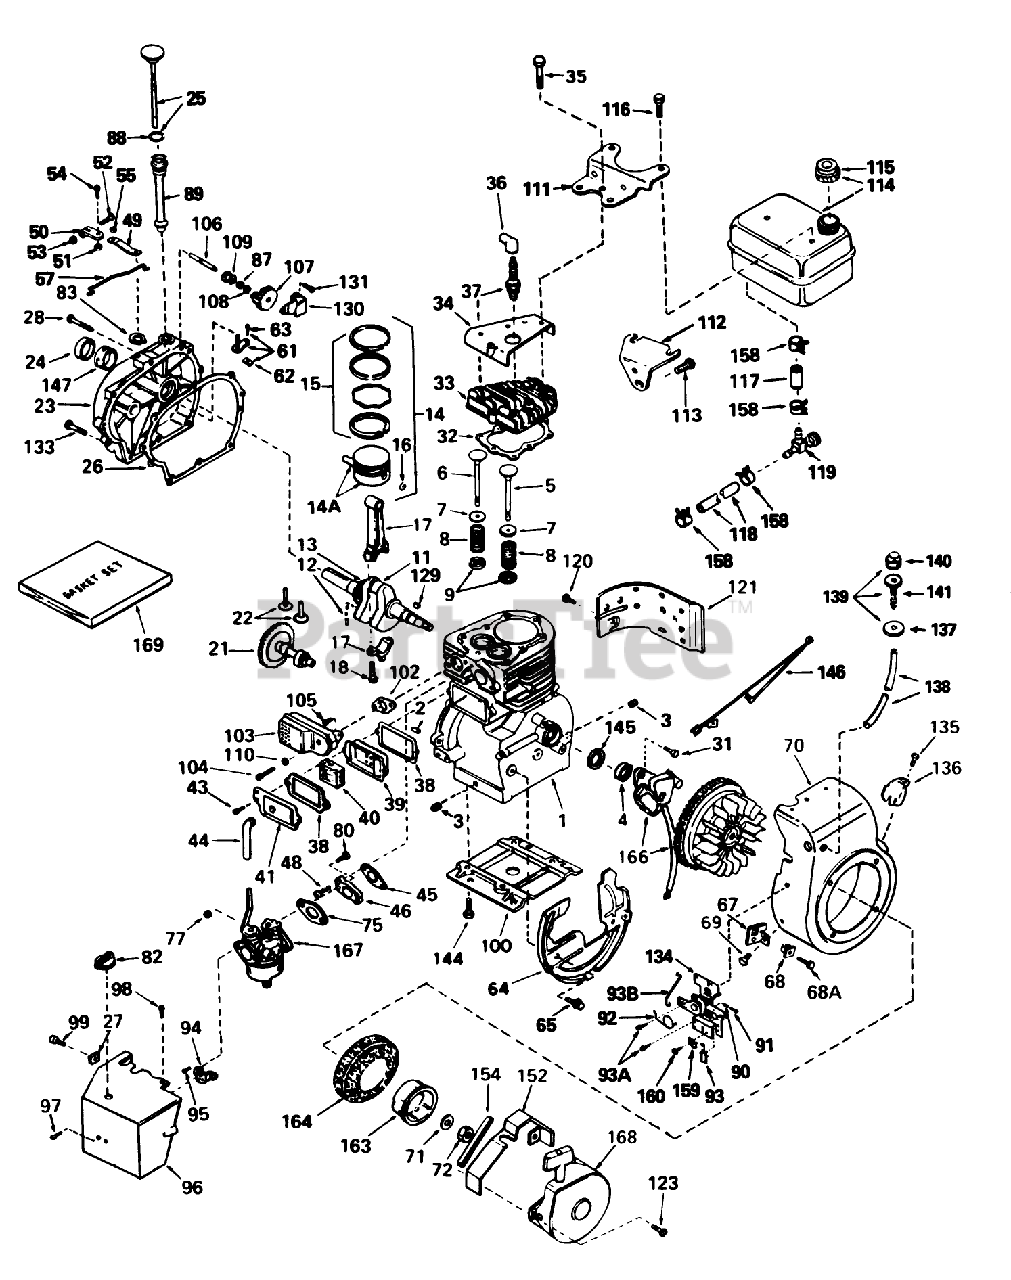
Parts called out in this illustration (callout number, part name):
1	Cylinder Assy. (Incl. Ref. #2, 3, 4 5)
2	Pin-Dowel
3	Plug-Drain, Oil (SQH 1/4-18)
4	Seal, Oil
5	Valve, Intake (Standard)(Incl. No. 9)
5	Valve, Intake (1/32" oversize)(Incl. No. 9)
6	Valve, Exhaust (Standard)(Incl. No. 9)
6	Valve, Exhaust (1/32" oversize)(Incl. No. 9)
7	Cap-Spring, Valve
8	Spring-Valve
9	Keeper-Spring, Valve
11	Crankshaft Assy. (Incl. Nos. 12 13)
12	Pin, Groove
13	Gear-Crankshaft
14	Piston, Pin Ring Assy. (Std.)(Incl. Ref. #14A, 15 16)
14	Piston, Pin Ring Assy. (.010 Oversize)(Incl. Ref. #14A, 15 16)
14	Piston, Pin Ring Assy. (.020 Oversize)(Incl. Ref. #14A,15 16)
14A	Piston Pin Assy. (Std.)(Incl. Ref. #16)
14A	Piston Pin Assy. (.010 Oversize)(Incl. Ref. #16)
14A	Piston Pin Assy. (.020 Oversize)(Incl. Ref. #16)
15	Ring Set, Piston (Std.)
15	Ring Set, Piston (.010 Oversize)
15	Ring Set, Piston (.020 oversize)
17	Rod Assy., Connecting (Incl. Ref. #18)
18	Bolt, Connecting Rod
21	Camshaft, BCR
22	Lifter-Valve
23	Cover, Cylinder (Incl. Nos. 24 106)
24	Oil Seal
25	Dipstick, Oil (Incl. Ref. #88)
26	Gasket-Cover, Cylinder
27	Nut-U Type
28	Screw (1/4-20 x 1-1/4)
31	Screw
32	Gasket-Head, Cylinder
33	CYLINDER HEAD
34	Cover-Head, Cylinder
35	Screw (5/16-18 X 2-1/2)
36	Cover-Spark Plug
37	Plug, Spark (J17LM or equiv.)
37	Plug, Spark (Champion RCJ-8)
38	Gasket-Breather
39	Body-Breather
40	Element-Breather
41	Cover-Valve
43	Screw
44	Tube-Breather
45	Gasket-Intake
46	Flange, Carburetor (Incl. Nos. 77 80)
48	Screw
49	Lever-Governor
50	Clamp-Lever, Governor
51	Nut-Lock
52	Screw
53	Nut-Lock
54	Screw
55	Washer-Lock
57	Governor Link
61	Rod, Governor (Incl. Nos.62 63)
62	Yoke-Governor
63	Screw (6-40x5/16)
64	Baffle Blower Housing
65	Screw (1/4-20x19/32)
67	Bracket
68	Grommet
68A	Screw
69	Screw, Hex Hd.
70	Housing, Blower (Incl. Ref. #135 136)
71	Washer
75	Gasket-Carburetor
77	Nut and Lock Washer (1/4-28)
80	Screw
82	Knob-Control
83	Ring-Retaining
87	Washer-Flat
88	O-Ring
89	Tube Fill
90	Spring-Compression
91	Screw
92	Spring-Throttle
93	Terminal
93A	Screw (10-32 x 1/2)
93B	Link-Throttle
94	Bracket-Choke
95	Screw (10-32 x 1/2)
96	Cover, Carburetor
97	Screw (8-32 X 5/16)
98	Screw (10-32x1/2)
99	Screw (8-32 x 3/8)
100	Base Engine
102	Gasket Exhaust
103	Muffler
104	Screw (5/16-18 X 2)
105	Screw
106	Shaft-Governor
107	Governor Gear ASM
108	Ring-Retaining
109	Spool, Governor
110	Washer
111	Plate, Fuel Tank Mounting
112	Bracket, Fuel Tank-Lower
113	Screw (1/4-20x19/32)
114	53023/VAR.10/16HP O
115	Cap, Fuel
116	Screw (1/4-15x7/8)
117	Line-Fuel
118	Line-Fuel (8.62)
119	Valve-Shut Off
120	Screw
121	Emnsion, Blower Housing
123	Screw
129	Key, Flywheel
130	Bracket, Governor
131	Screw (10-32 x 35/64)
133	Screw
134	Control Assy., Remote Speed (Incl. Ref. #90 thru 93)
135	Screw (8-32 x 3/8)
136	Screw
137	Retainer, Primer Bulb
138	Line, Primer
139	Primer Assy. (Incl. Nos. 89, 90 91)
140	Bulb, Primer
141	Body, Primer
144	Screw
145	Gasket Stator
146	Wire, Ground
147	Bushing-Crankshaft
152	Guard-Starter
154	Seal, Snowguard
158	Clamp-Line, Fuel
159	Conduit
160	Screw (10-32 x 3/8)
163	Cup-Starter
164	Screen, Air
166	Magneto
167	Carburetor (Incl. Ref. #75)
168	Starter Assy., Rewind
169	Gasket Set (Incl. Items Marked *)
